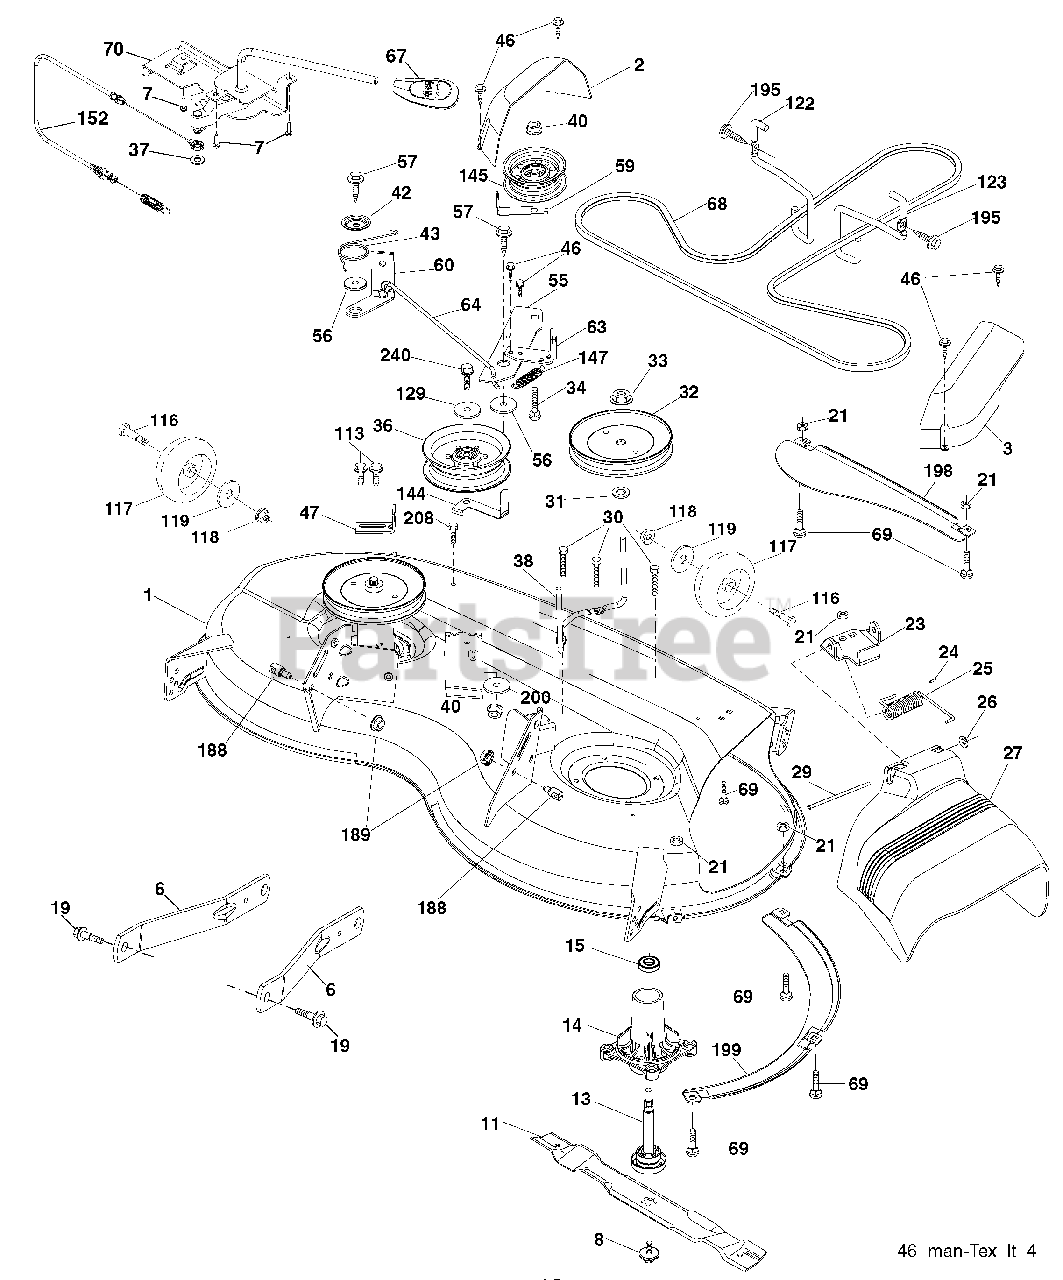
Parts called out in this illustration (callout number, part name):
1	Mower Housing
2	Cover Mandrel LH
3	Cover Mandrel RH
5	Retainer Spring
6	Arm Suspension
7	Screw #10 x 0.750
8	Bolt/Washer asm 7/16-20 unf
11	Blade, 46" Hi-Lift (For bagging or discharge)
13	Shaft Assembly, Mandrel
14	Housing, Mandrel
15	Bearing, Ball, Mandrel
19	Bolt, Shoulder
21	Nut, Crownlock 5/16-18 unc
23	Bracket, Deflector
24	Cap, Sleeve
25	Spring, Torsion, Deflector
26	Nut, Push
27	Shield, Deflector
29	Rod, Hinge
30	Screw Thdrol Rolling Wsh Hd
31	Washer, Spacer
32	Pulley, Mandrel
33	Nut, Toplock, Flanged
34	Bolt Carr Sh. 3/8-16 x 1-1/2 Gr.
36	Pulley, Idler, Flat
37	Washer 13/32 x 13/16 x 16 Ga.
38	Keeper Belt LH Mandrel
40	Nut, Lock Flg. 3/8-16 unc
42	Spring Torsion Brake
43	Spring Torsion Retainer
46	Screw Thd Roll 1/4-20 x 5/8
47	Bracket Clutch Cable
55	Arm, Idler
56	Spacer, Retainer
57	Screw Hexwsh Thd 3/8-16 x 1
59	Guard, Tuv Idler (94)
60	Arm Brake Mower
63	Arm Brake Mower
64	Linkage Brake
67	Handle, Clutch Cable
68	V-Belt
69	Bolt Rdhd Sqnk 5/16-18 x 5/8
70	Clutch Asm. Manual
113	Screw 5/16-18
116	Bolt SHLD
117	Wheel Gage
118	Nut Centerlock 3/8-16 unc
119	Washer 3/8 x 7/8 x 14 Ga.
122	Keeper Belt Eng. LH
123	Keeper Belt Eng. RH
129	Washer 13/32 x 13/16 x 12 Ga.
144	Keeper Belt
145	Pulley Idler
147	Spring Return
152	Cable Clutch Manual w/Spr.
188	Stud Fastener
189	Nut Lock Hex Flange
195	Screw Hexwsh Thdr 3/8-16 x 3/4
198	Baffle Center Front
199	Baffle Front RH
200	Washer 13/32 x 1/2 x 11 Ga.
208	Screw 3/8-16 x 1/2
240	Bolt Fin Hex 3/8-16 x 2-1/4 Gr. 5
240	Mandrel Assembly
240	Replacement Mower, Complete
